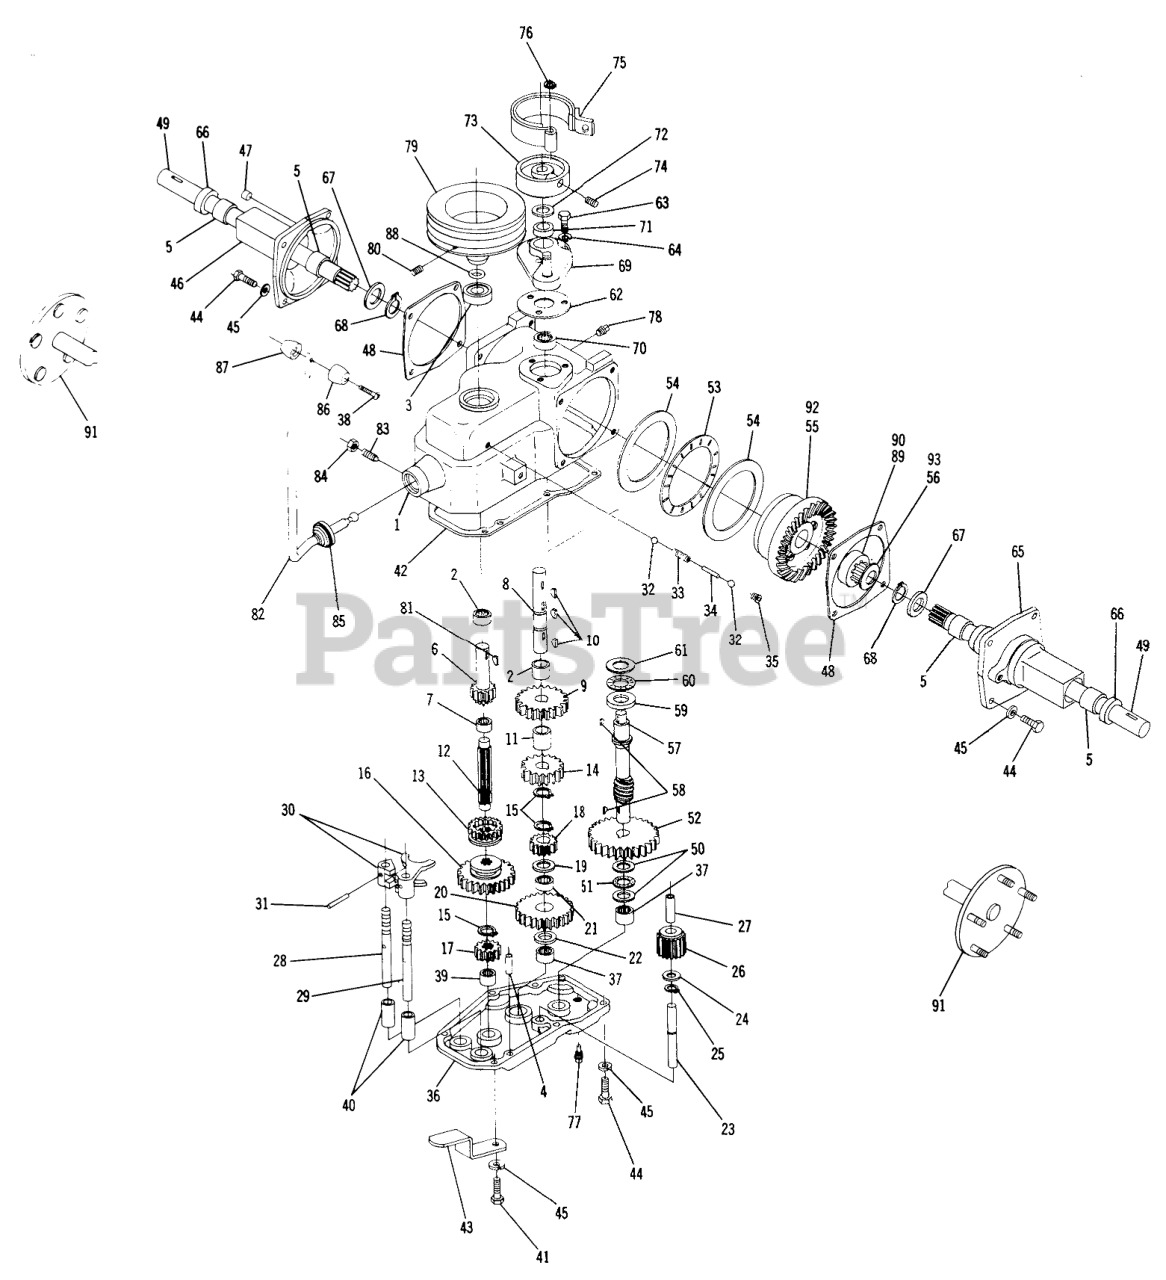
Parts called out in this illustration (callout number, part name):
1	Housing-Gear Case
2	BEARING-NEEDLE
4	PIN-DOWEL
5	BEARING-NEEDLE
7	BEARING-NEEDLE
8	Shaft Idler
17	GEAR
18	Gear-1st Speed
19	WASHER-THRUST
21	BEARING-NEEDLE
23	Shaft-Reverse Idler
24	RACE THRUST
26	GEAR/BUSHING ASM-REVERSE IDLER
27	BUSHING
28	RAIL-SHIFT
29	RAIL-REAR SHIFT
31	PIN-ROLL
32	BALL-DETENT
34	PIN-SHIFT
37	BEARING-NEEDLE
38	Bolt #10-24 x 1 1/4
40	Bushing-Shifter Rail
41	Bolt 3/8-16 x 1
44	Bolt 3/8-16 x 1
45	Lockwasher
55	BULLT 325
58	KEY WOODRUFF
61	Rae-Thrust
63	Bolt 5/16-18 x
64	Lockwasher
65	Disc 8" Wheel
72	WASHER-THRUST
74	Screw 1/4-20 x 5/8
77	Plug 1/4 Pipe
80	Set Screw-Nylok
81	Key
83	SETSCREW
84	Nut 1/4-20
86	KNOB
87	KNOB
88	O-Ring
89	Bearing Axle
90	Bearing Axle
91	Axle
92	BULLT 325
